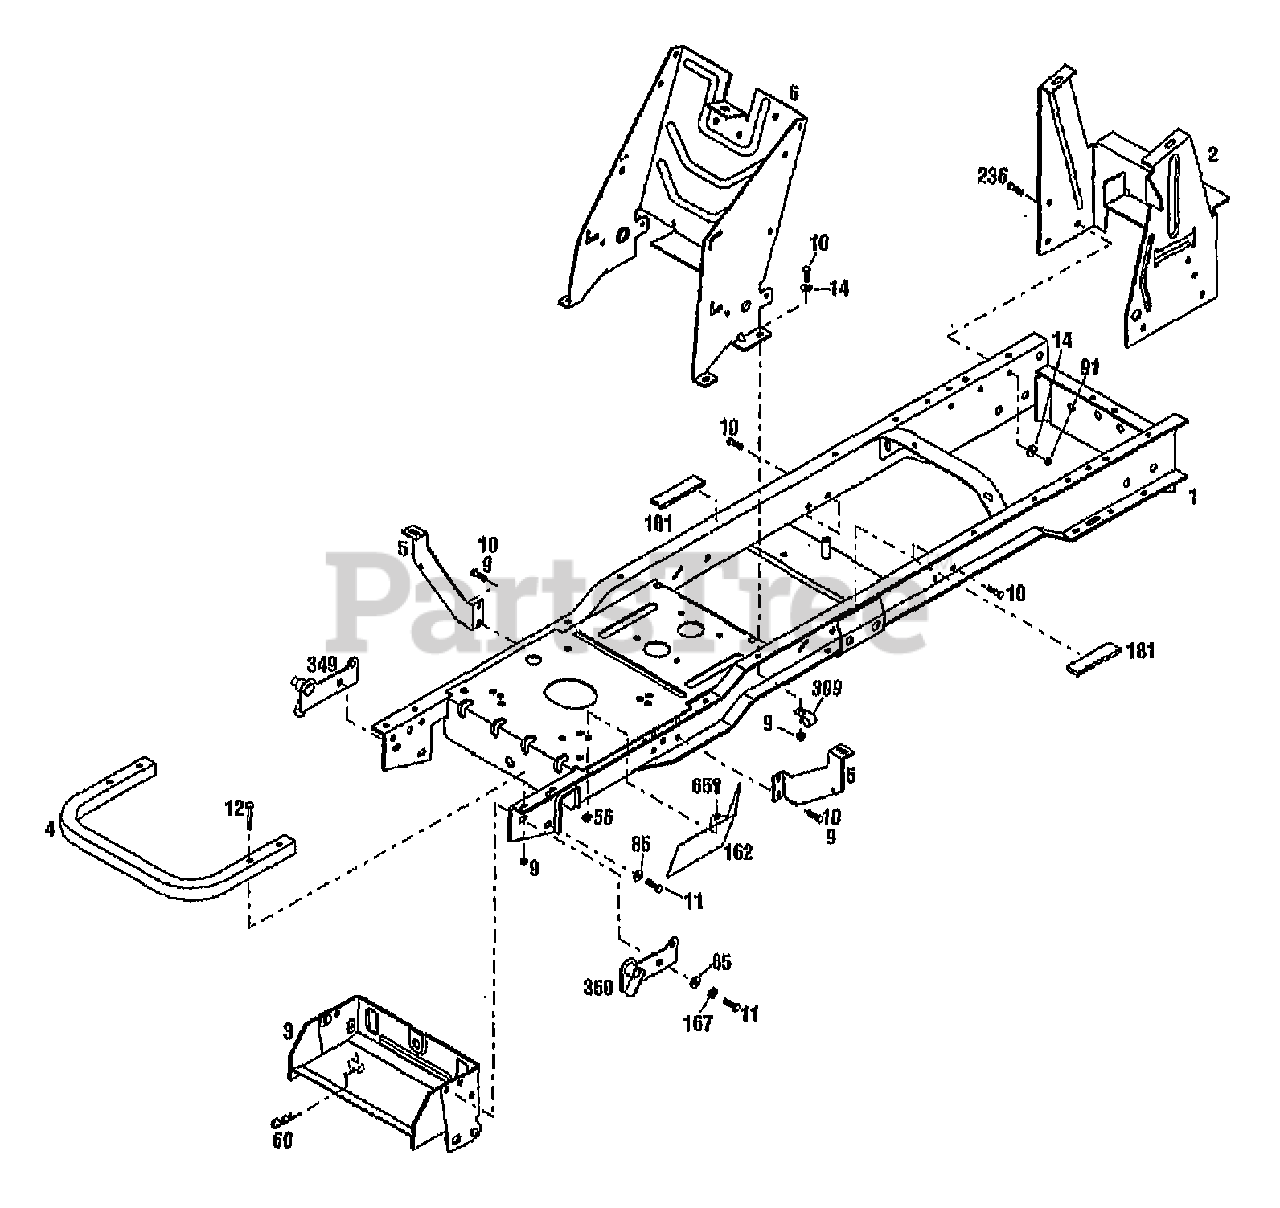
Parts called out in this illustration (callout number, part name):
1	ASSM-FRAME LTX
2	SUPPORT-REAR TANK
3	ASSM-BRKT ATTACHMENT
4	BUMPER-FRONT
5	SUPPORT-FENDER
6	SUPPORT-CONSOLE
9	NUT-HFLK 5/16-18 ZP
10	SCR-HHC 5/16-18X.75 GR 5 ZP
11	SCR-HH 3/8-16X1.0 G5 ZP
12	SCR-HH 5/16-18X1.75
14	WASHER-FLAT 5/16 SAE
56	NUT-HF/LK 1/4-20 ZP
60	PIN-HITCH .125X2.56 ZP
65	SCR-HH 1/4-20X.625
85	WASHER-FLAT 3/8 SAE
91	NUT-TOP/LK 5/16-18 ZP
162	SHIELD-HEAT UPPER
167	WASHER-LK .375 @ DEPL
236	SCR-HFLK 5/16-18X.75 ZP
309	CLIP-J
349	PLATE-PIVOT RH
350	PLATE-PIVOT LH
